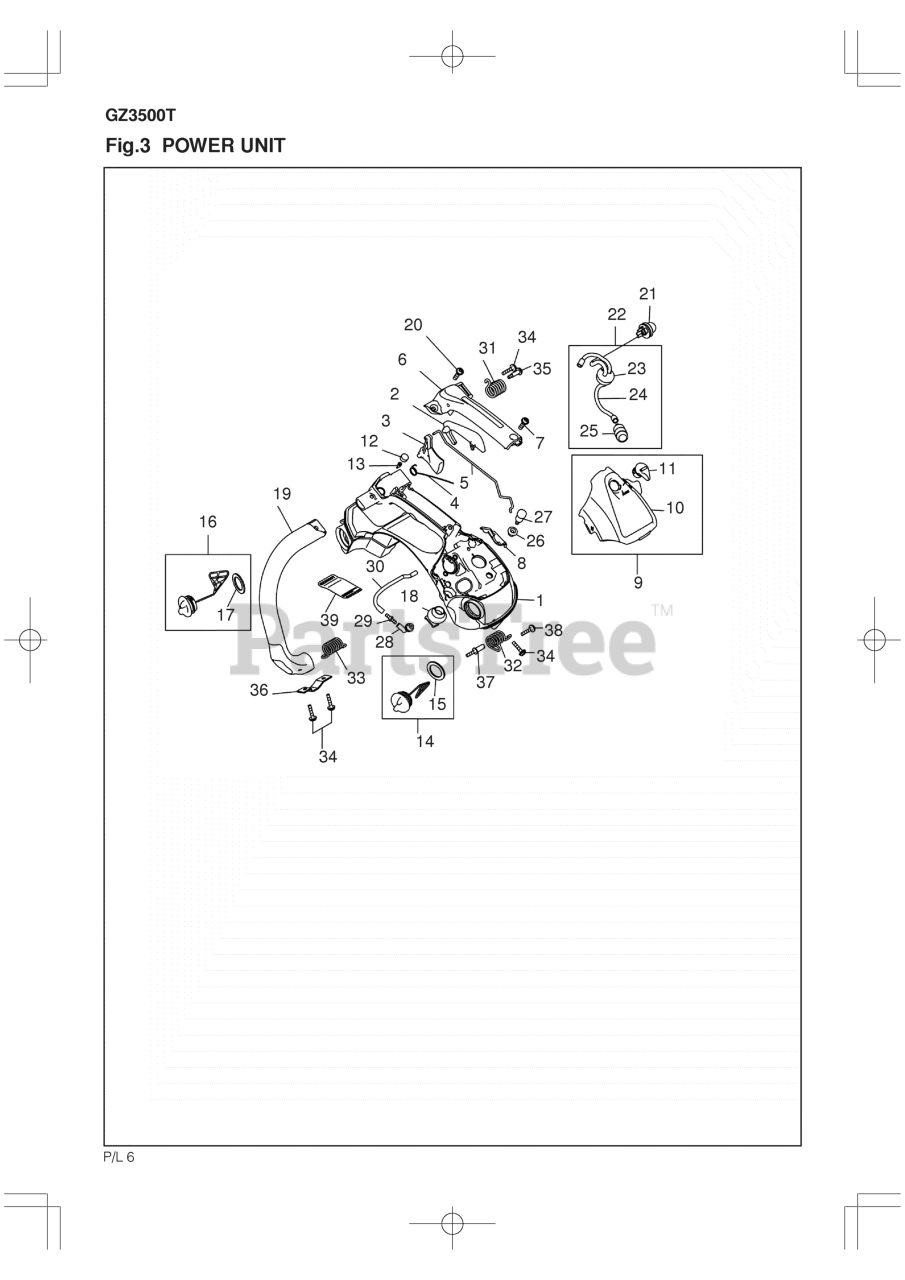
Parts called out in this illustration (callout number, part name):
1	HANDLE, COMP
2	ARM
3	LEVER, TH
4	SPRING
5	ROD, TH
6	COVER, GRIP
7	SCREW
8	BRACKET, KNOB
9	COVER COMP
10	CIVERN CLEANER
11	KNOB
12	SEAL
14	CAP ASSY
15	GASKET
16	CAP ASSY
17	GASKET
18	PIPE, AIR
19	L, HANDLE
20	SCREW
21	PUMP ASSEMBLY
22	PIPE ASSY
23	GROMMET
26	GROMMET
27	BREATHER ASSEMBLY
28	PIPE
29	JOINT
30	PIPE
31	SPRING, FRONT
32	SPRING, PTO
33	DAMPER, MAG
34	SCREW
35	SCREW
36	ANTI VIBRATION STRAP
38	SCREW
39	LABEL, CE
